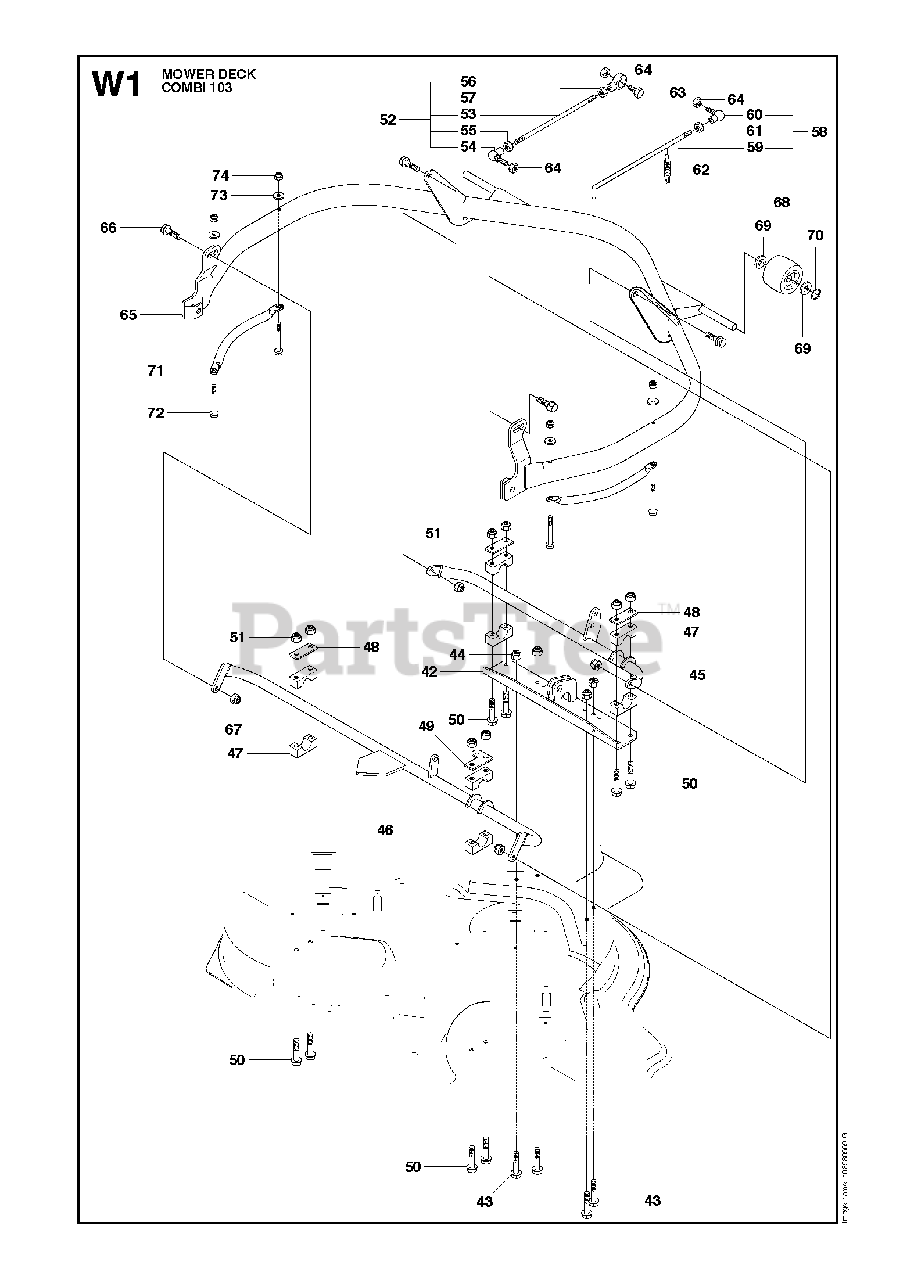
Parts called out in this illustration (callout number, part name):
3	NUT
4	PLUG
5	BOLT
6	RP SPINDLE ASSY
7	SHAFT
8	BEARING
9	SPACER
10	BEARING HOUSING
11	RP SPINDLE ASSY
12	SHAFT
13	BEARING
14	SPACER
15	BEARING HOUSING
17	WASHER BRB 8.4X17
18	LOCKNUT M8
26	BLADE
29	BELT TENSIONER ASSY
30	BELT TENSIONING ARM
31	PULLEY
32	SPACER
33	BOLT
34	WASHER
36	LOCKNUT M8
38	BELT
44	LOCKNUT M8
51	LOCKNUT M8
52	PARALLEL RODY ASSY
53	ROD
54	LINK
55	NUT
56	LINK
57	NUT
58	CLUTCH ROD ASSY
59	ROD
60	LINK
61	NUT
67	LOCKNUT M8
68	DECK ROLLER, FRONT
70	RETAINING RING SGA 15
73	WASHER
74	LOCKNUT M6
